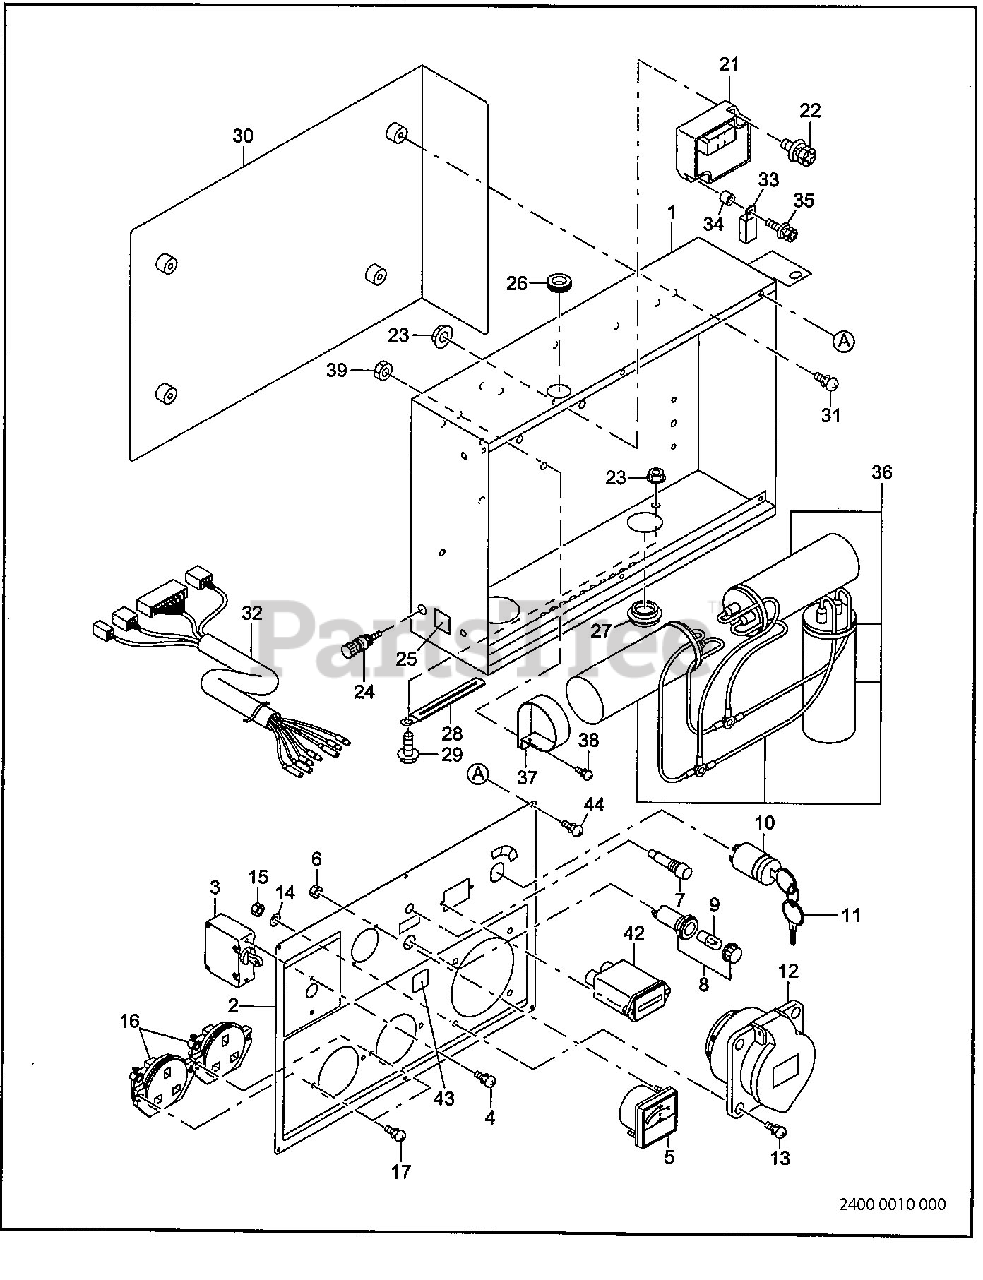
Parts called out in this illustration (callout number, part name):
1	CONTROL BOXASSY
1	CONTROL BOX UNIT
2	CONTROL PANEL ASSY
2	CONTROL PANEL
3	NO FUSE BREAKER (1P-35A)
4	SCREW and WASHER ASSY
8	LAMP (OIL)
9	LAMP (18V-0.11A)
10	KEY SWITCH
12	AC RECEPTACLE (240V-32A)
13	SCREW and WASHER ASSY
16	AC RECEPTACLE (250V-16A)
17	SCREW
21	ECU (O/S & R/C) ASSY
22	SCREW and WASHER ASSY
23	FLANGE NUT
29	FLANGE BOLT
31	SCREW and WASHER ASSY
32	WIRE ASSY
35	SCREW
36	CONDENSER ASSY
37	CONDENSER BRACKET
38	SCREW and WASHER ASSY
44	SCREW and WASHER ASSY
